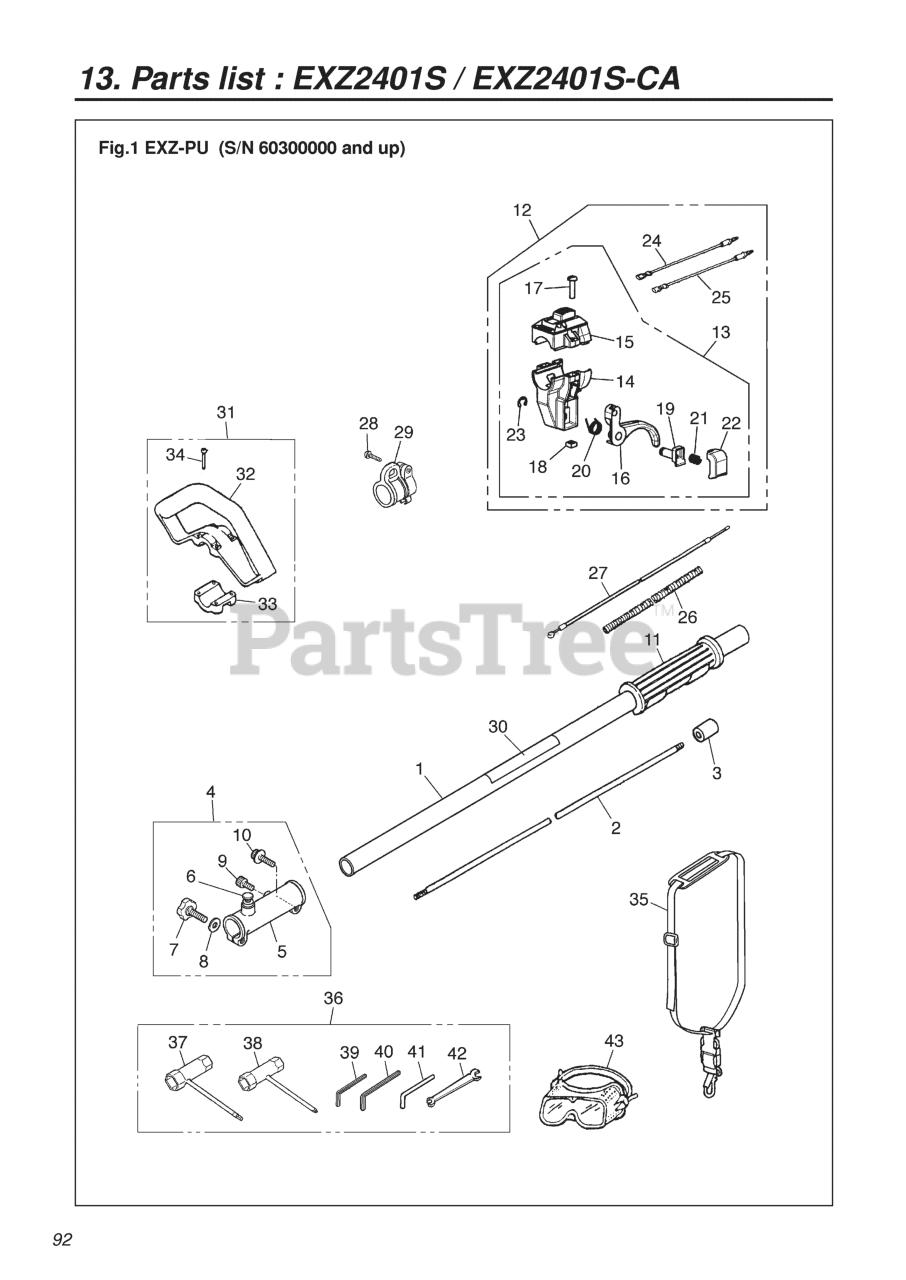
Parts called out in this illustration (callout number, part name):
1	PIPE COMP
2	SHAFT
3	SPACER
4	JOINT, PIPE ASSY
5	JOINT
6	STOPPER COMPLETE
7	BOLT, KNOB
8	WASHER, M8 x 2.3 (RPLS -20823)
9	BOLT, M5 X 10
10	BOLT, M6 x 1.35
11	GRIP
12	LEVER ASSY
13	LEVER
15	COVER
16	FLEX, TRIGGER
24	CORD (A), BLACK
25	CORD (B), RED
26	TUBE (RPLS 4900-72141)
27	CABLE (RPLS 5580-83100)
28	HANGER COMP.
29	SCREW, M5X20 (RPLS.1400-75510)
30	PLATE, NAME
31	HANDLE ASSEMBLY
32	HANDLE
34	SCREW, M5 x 35
35	STRAP ASSY.
36	TOOL SET
37	SOCKET
38	SOCKET
39	WRENCH (TOOL)
40	WRENCH (TOOL)
41	BAR
42	SPANNER, 8 X 10 (RPLS 2540- )
43	GOGGLE
